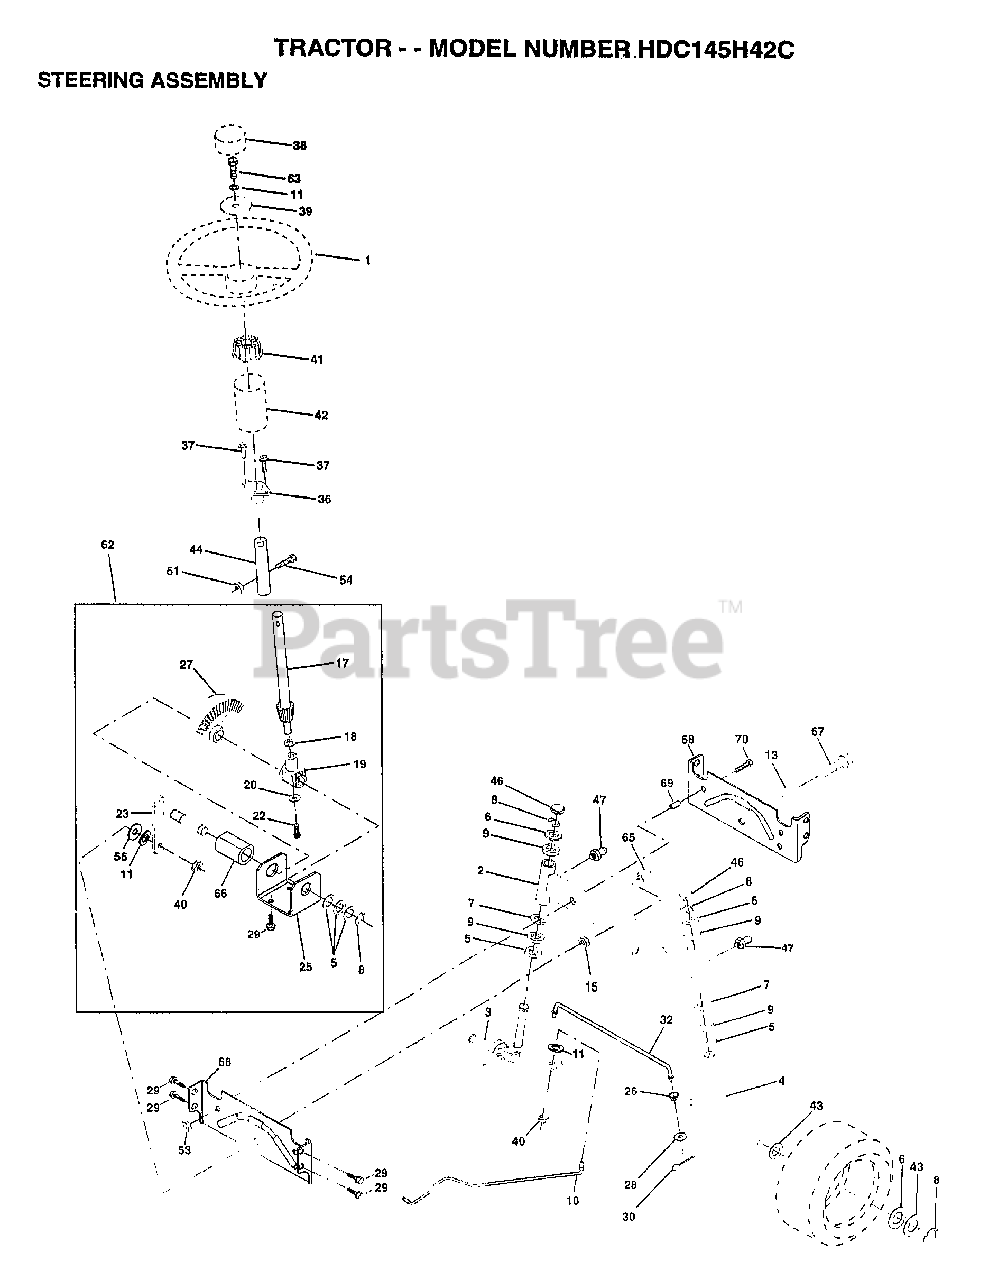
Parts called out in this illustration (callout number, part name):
1	WHEEL STR AYP BLK
2	AXLE ASM
3	SPINDLE ASM LH
4	"SPINDLE ASM,RH"
5	WASHER .T
6	WASHER
7	WASHER
8	RING
9	COL. SRTG. BEAR.
10	DRAGLINK-STAMPED
11	LOCKWASHER
13	BEARING AXLE
15	"NUT-LOC,FLANGE LT"
17	SHAFT ASM STEERIN
18	THRUST WASHER
19	SUPPORT.SHAFT
21	LOCKWASHER
22	CONFLICT W/PART #
25	BRKT-STEERING
26	BUSHING.DRAGLINK
27	GEAR SECTOR
28	WASHER
29	SCREW
30	COTTER PIN
32	TIE ROD
36	BUSHING.STEERING
37	"SCREW-TT,10-32 FL"
38	CAP STEER AYP
39	WASHER T
40	GRIPCO NUT
41	ADAPTER LT
42	BOOT.STEER.PL
43	WASHER
44	EXT SHAFT STEERIN
46	CAP
47	ZERK M
51	NUT
54	BOLT
62	KIT STEERING ASM
63	BOLT
65	SPACER AXLE
66	"BEARING-ARM,PITMA"
67	BOLT
68	BRACE AXLE
69	"SPACER BRCAE,AXLE"
70	BOLT.HEX.3/8-16X2
